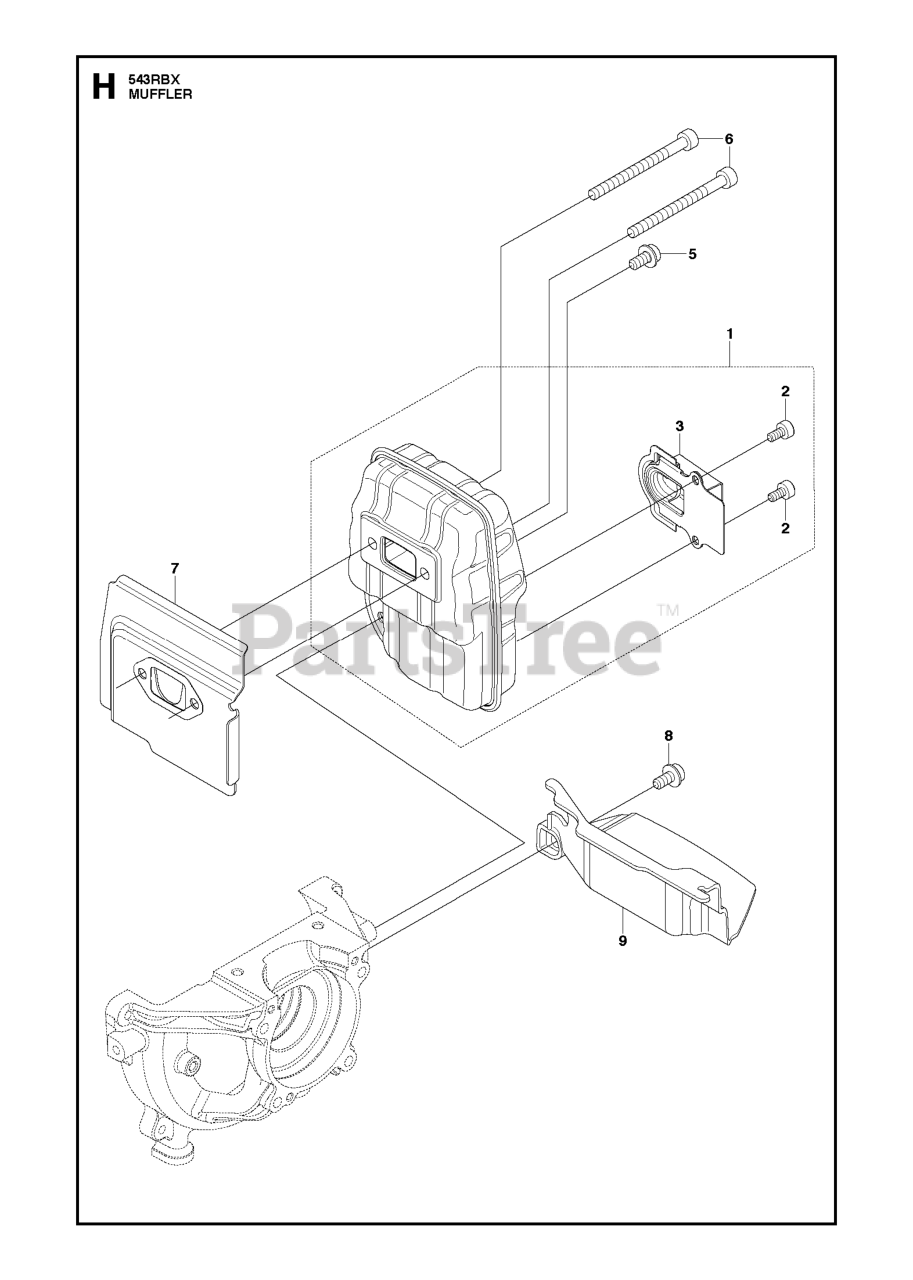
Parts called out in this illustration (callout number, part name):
1	MUFFLER ASSY
5	BOLT (RPLS T495051010-11)
6	BOLT
8	BOLT (RPLS T495051010-11)
